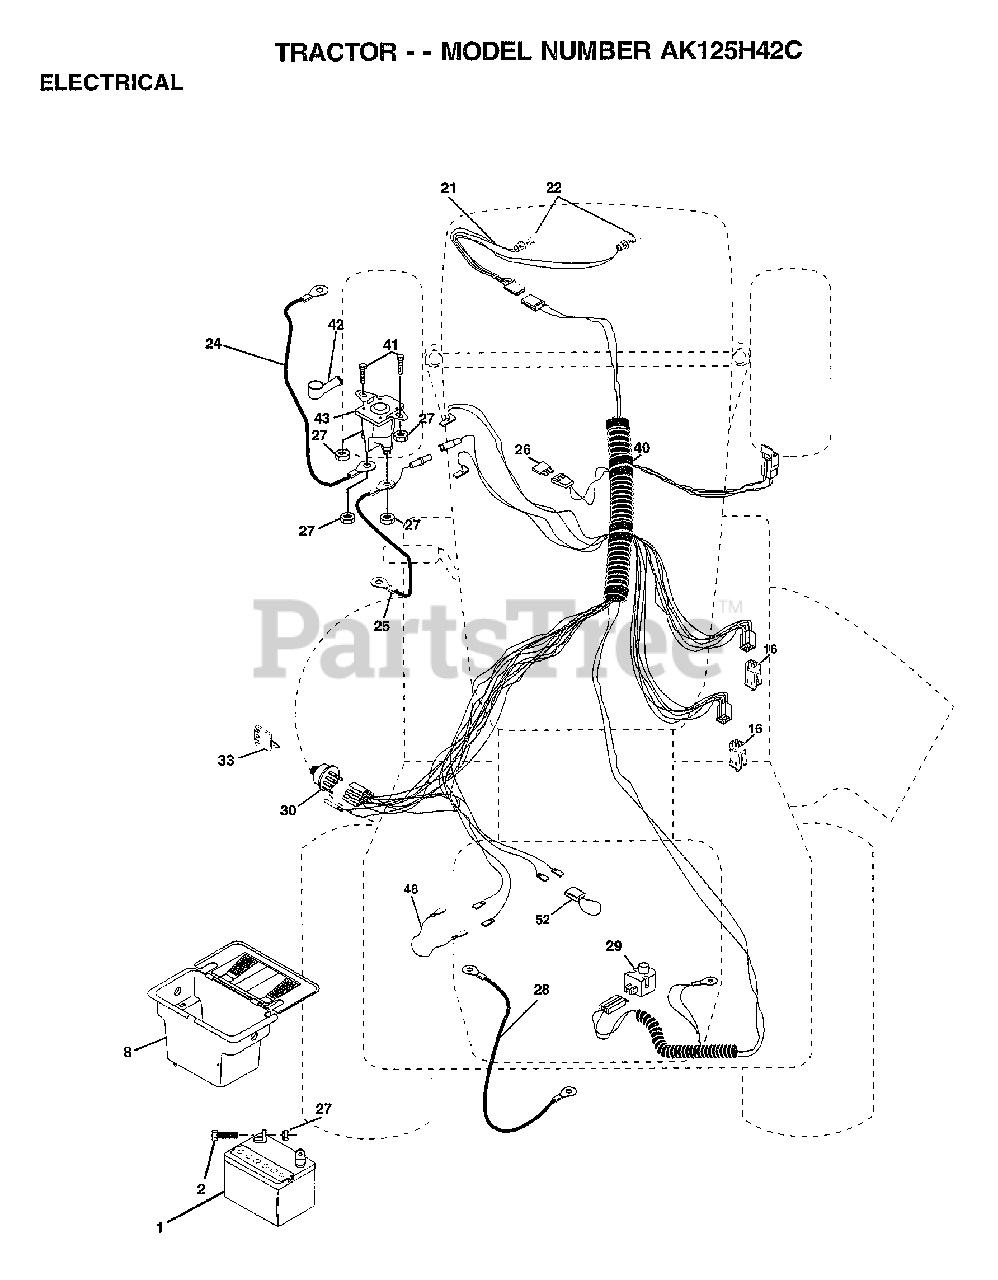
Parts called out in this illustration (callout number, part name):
2	BOLT LT
8	"CASE,BATTERY.MECH"
16	SWITCH INTERLOCK
21	HARNESS.ASM.LIGHT W/4152J
22	HEADLAMP BULB
24	"CABLE T, BATTERY"
25	CABLE.BTRY.6GA.RD
26	FUSE.15 AMP
27	NUT
28	CABLE T
29	SWITCH SEAT
30	SWITCH.IGN.
33	KEY MLD GEN DELTA
40	HARNESS IGN
41	BOLT HXHD FIN
48	ADAPTER AMMETER
52	PROTECTION LOOP
